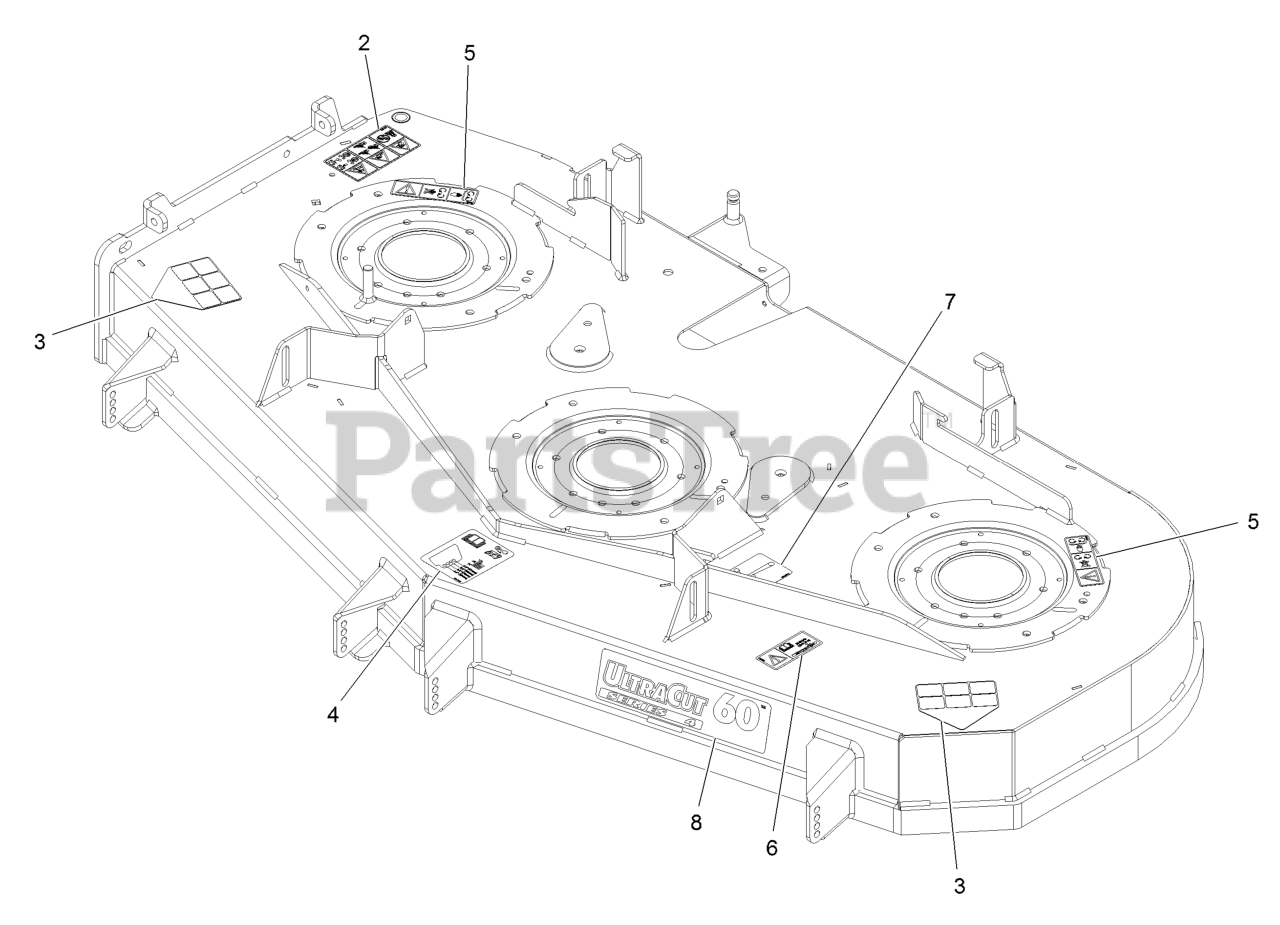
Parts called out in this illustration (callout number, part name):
2	DECAL-DANGER
3	DECAL-DANGER
4	DECAL-ROLLER, ANTI-SCALP
5	DECAL-COVER, MISSING
6	DECAL-BOLT TORQUE
7	DECAL-ROUTING, BELT
8	DECAL,ULTRACUT 60 SERIES
